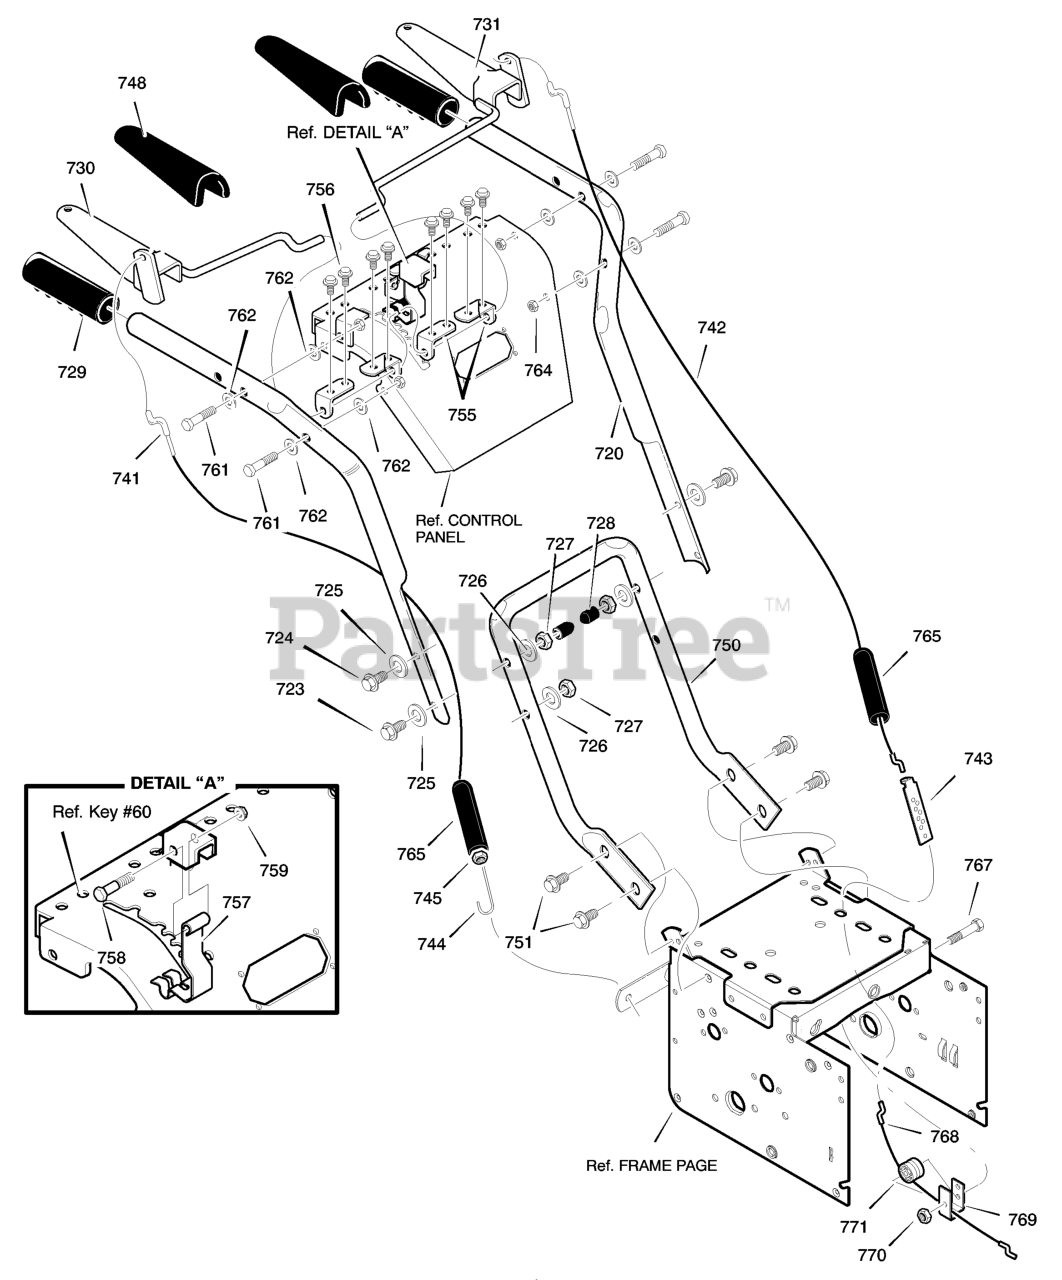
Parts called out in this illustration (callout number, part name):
720	HANDLE, UPPER LH
721	HANDLE, UPPER RH
723	SCREW
724	SCREW
725	WASHER, FLAT
726	WASHER, SPTLK
727	NUT, REGHEX
728	STOP, PLASTIC
729	GRIP-HANDLE
730	LEVER, ASSY CLUTCH DRIVE RH
731	LEVER, ASSY CLUTCH DRIVE LH
741	CABLE, AUGER CLUTCH
742	CABLE, AUGER DRIVE
743	BRACKET, CABLE ADJUSTER
744	SPRING, AUGER CLUTCH
745	NUT, 1/4-20
748	GRIP, CLUTCH HANDLE
750	HANDLE, LOWER
751	SCREW
754	SCREW
755	BRKT, ROD
756	SCREW
757	SPRING, CAM LOCK
758	BOLT, HEX
759	NUT
761	SCREW
762	WASHER, FLAT
764	NUT, HEXFLNG
765	BOOT, CLUTCH SPRING
767	BOLT, HEX 1/4-20 X 1.50
768	CABLE, LOWER DRIVE 12"
769	BRACKET, CABLE SPOOL YZ
770	NUT
771	SPOOL-CABLE, AUGRT CLUTCH
